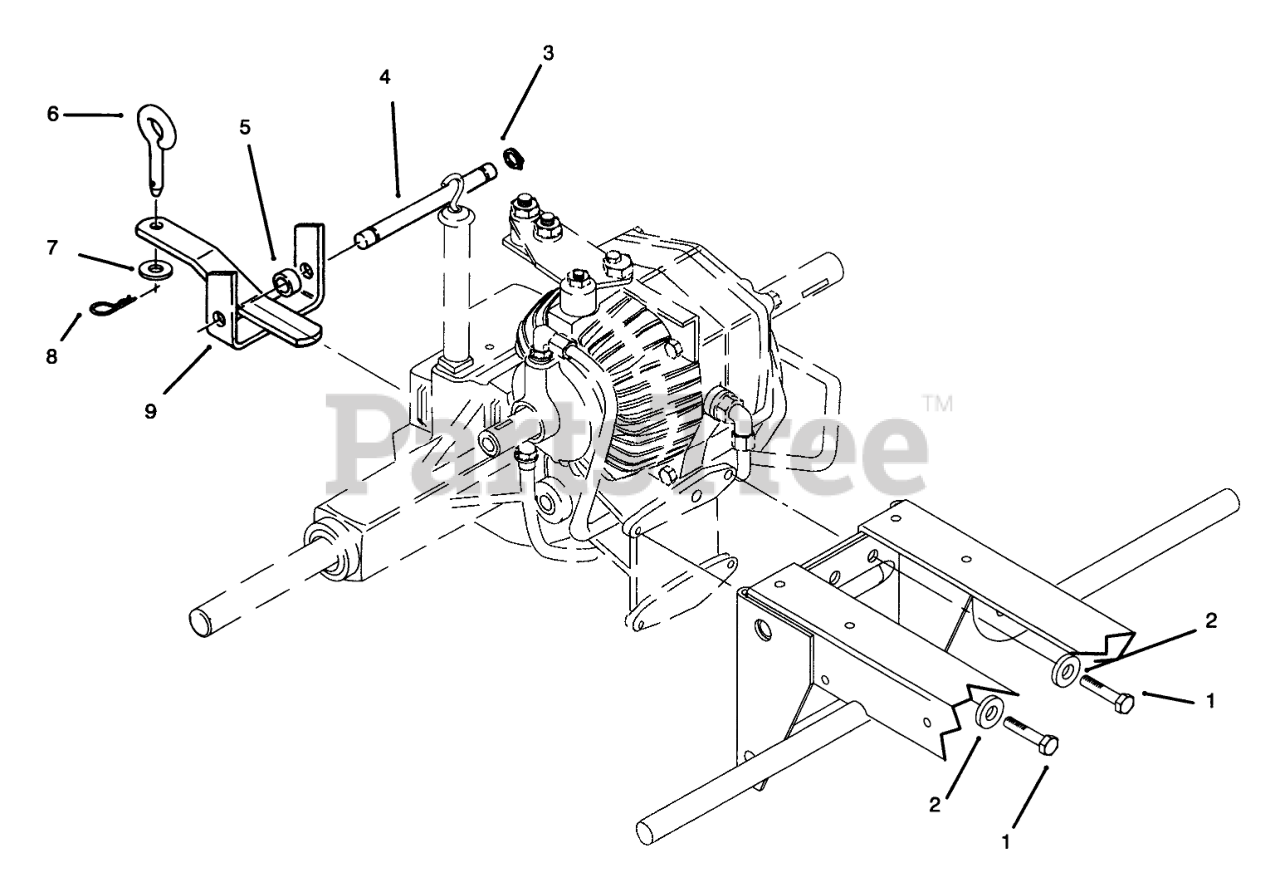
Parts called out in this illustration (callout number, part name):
1	SCREW-HH
2	WASHER-LOCK
3	E-RING
4	PIN-STATIONARY HITCH
5	Spacer
6	PIN-TOOL
7	WASHER-FLAT
8	Hairpin Cotter
9	Hitch
